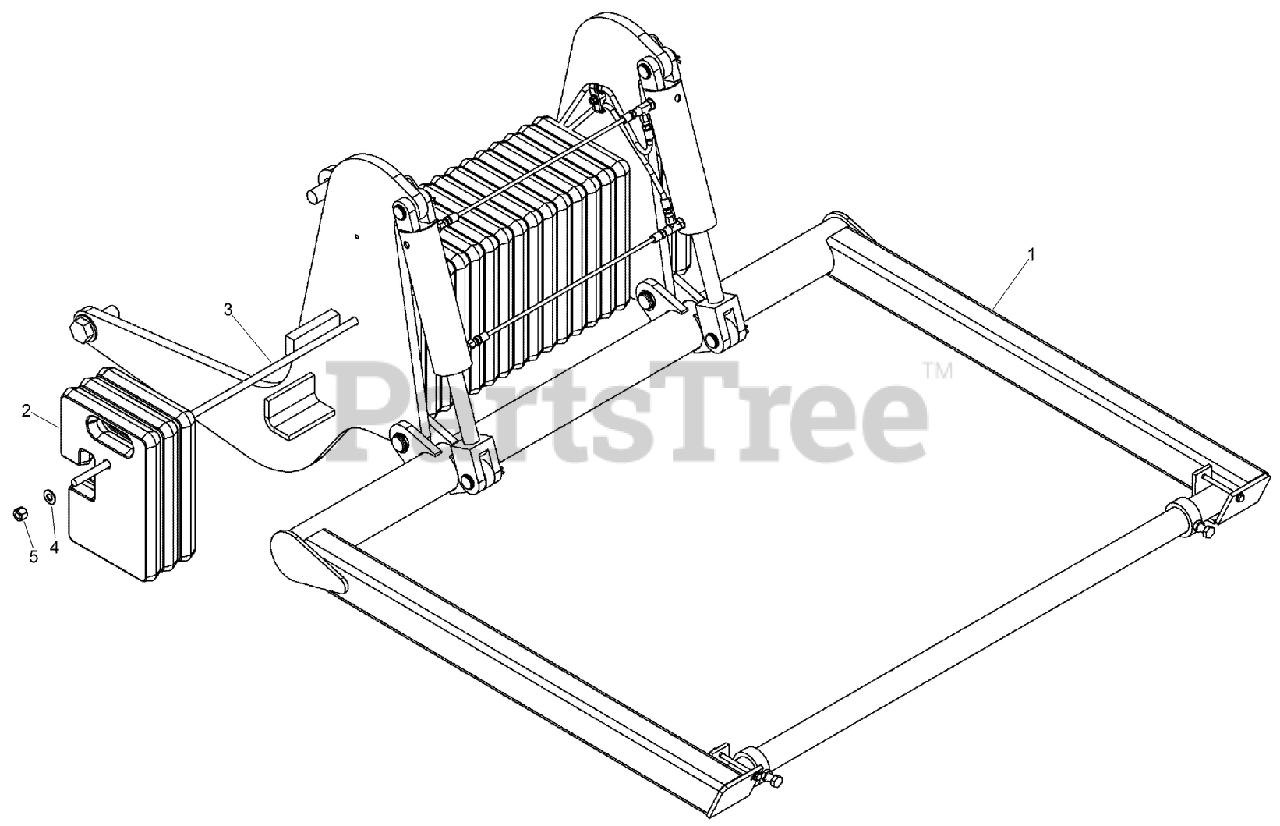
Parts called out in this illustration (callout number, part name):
1	REEL CARRIER ASM
2	COUNTERWEIGHT-60lb
3	ROD-WEIGHT
4	WASHER-FLAT
5	NUT-LOCK, HEX
